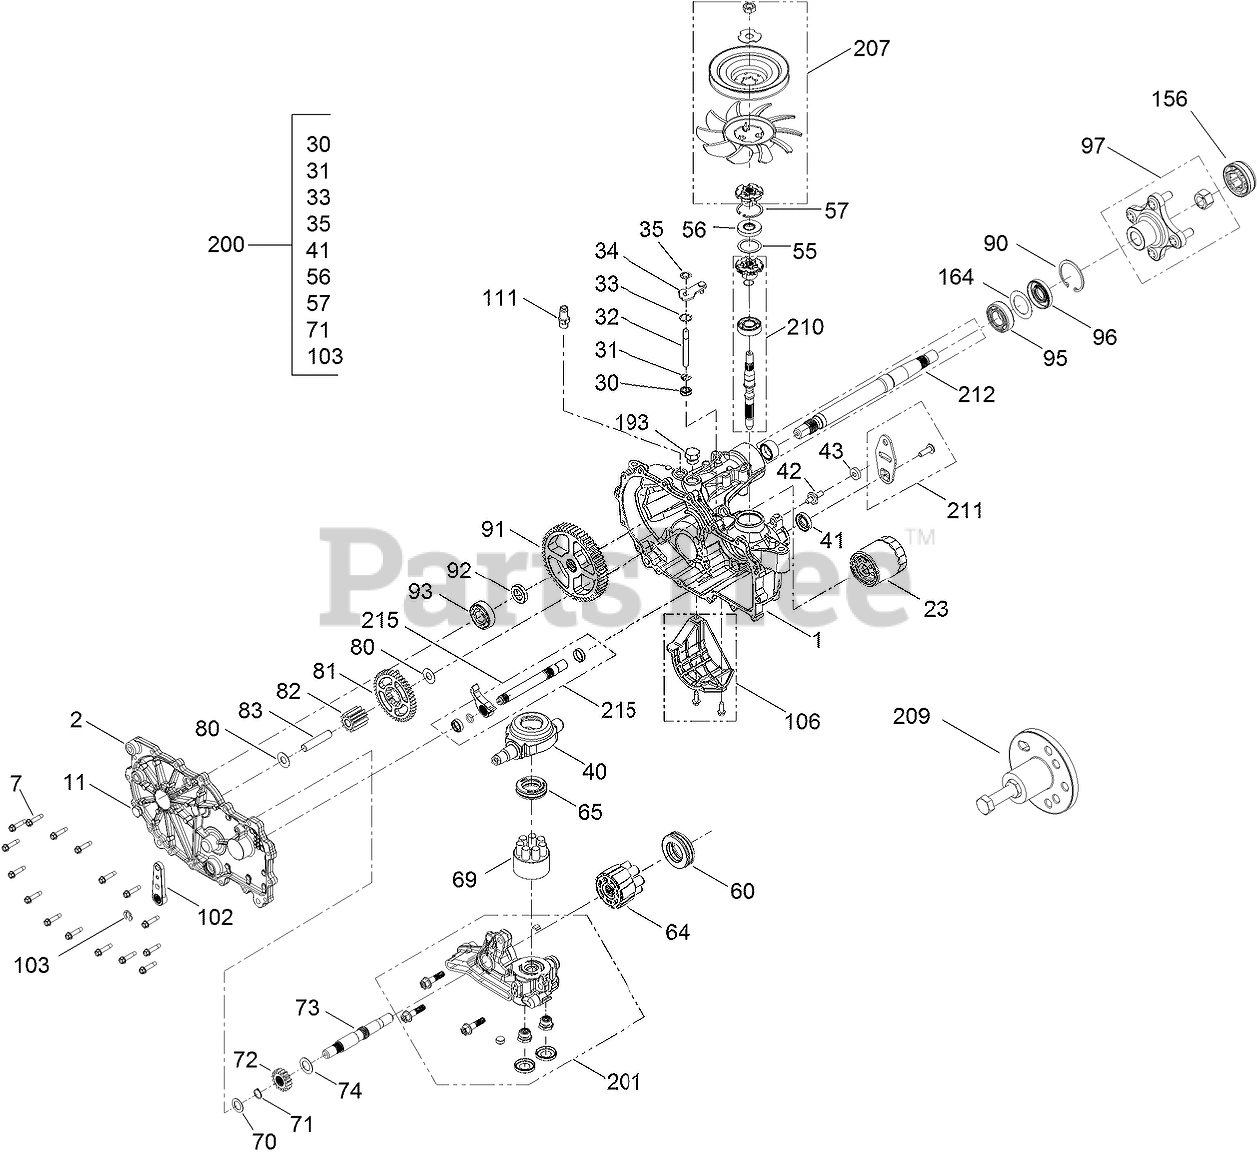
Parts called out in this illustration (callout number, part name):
1	KIT-HOUSING MAIN LH, CNTL
2	LH SIDE COVER KIT
7	SCREW-HHF
23	ELEMENT-OIL FILTER, HYD
30	SEAL-LIP
31	RING-RETAINING, EXTERNAL
32	ROD-BYPASS
33	RING-RETAINING, INTERNAL
34	ARM-BYPASS
35	RING-RETAINING, EXTERNAL
40	SWASHPLATE-TRUNNION
41	SEAL-LIP
43	PUCK-FRICTION
55	SPACER
56	SEAL-LIP
57	RING-RETAINING
60	BEARING-THRUST
64	CYLINDER BLOCK ASM KIT
65	BEARING-THRUST
69	PUMP BLOCK ASM
70	WASHER-FLAT
71	RING-RETAINING
72	GEAR-16T
73	SHAFT-MOTOR
74	WASHER
80	WASHER
81	GEAR-43T
82	GEAR-11T
83	PIN-JACKSHAFT
90	RING-RETAINING
91	GEAR-54T
92	SPACER
93	BEARING KIT
95	BEARING-BALL
97	HUB KIT
102	HANDLE-BRAKE
103	RING-RETAINING, EXT
106	FILTER GUARD KIT
111	ADAPTER-STRAIGHT
156	COVER-NUT, AXLE
164	SPACER
200	SEAL KIT
201	CENTER SECTION KIT
207	FAN AND PULLEY KIT
210	KIT-INPUT SHAFT
211	CONTROL ARM KIT
212	AXLE SHAFT KIT
215	INBOARD KIT
